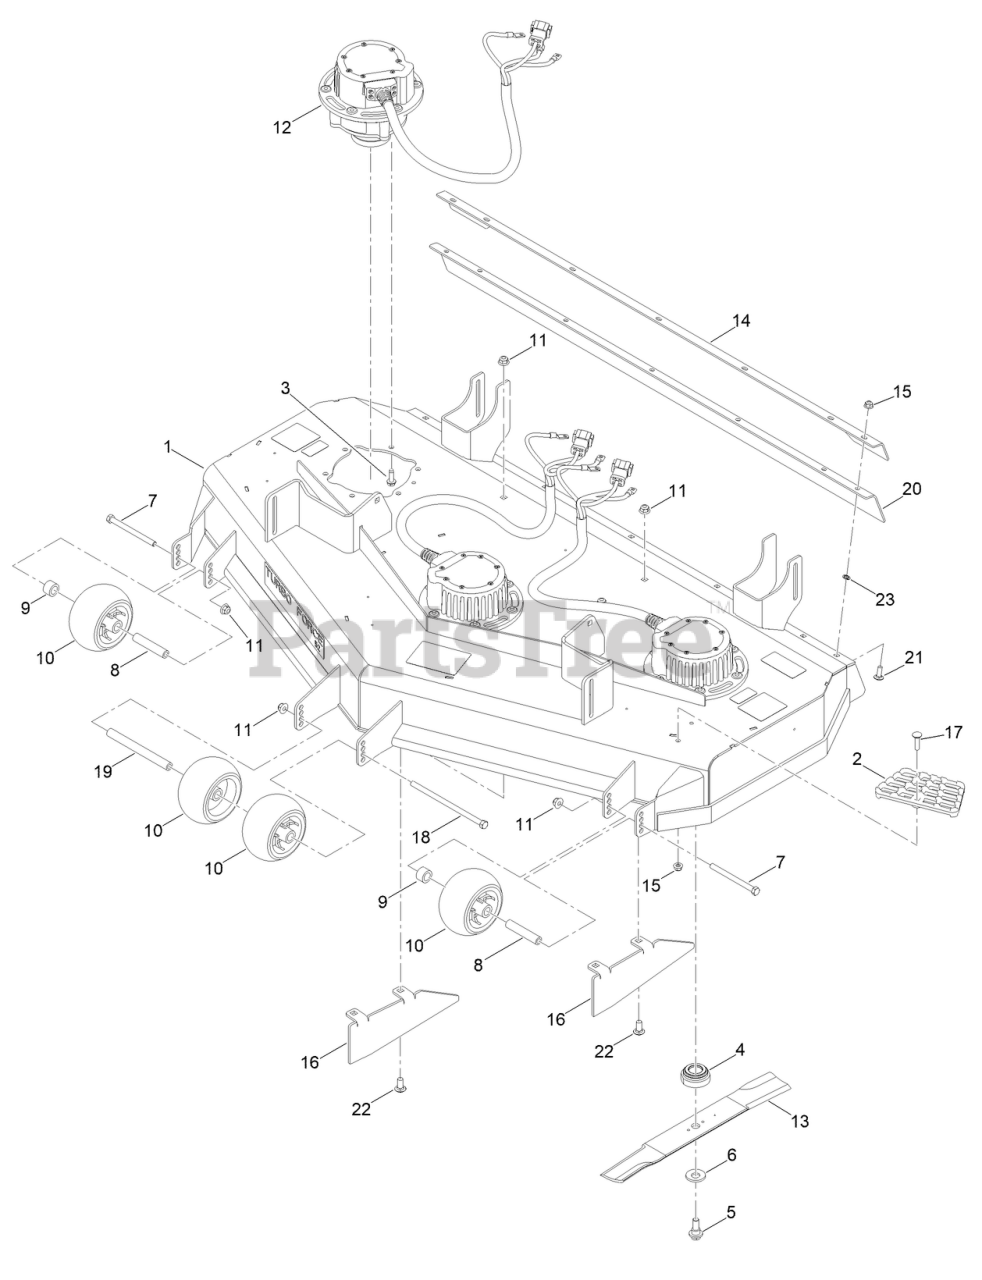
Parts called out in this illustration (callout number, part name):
1	DECK ASM-52IN, RD
2	STEP-DECK
3	SCREW-THD ROLL, HWH
4	RETAINER-BLADE
5	SCREW-SHOULDER,HWH
6	WASHER-BELLEVILLE
7	SCREW-HH
8	TUBE-SHAFTING
9	TUBE-SPACER
10	ROLLER-SCALP, ANTI
11	NUT-HF, NI
12	MOTOR/GEN-48V,
13	BLADE-18.0IN, MED SAIL
14	DEFLECTOR, BRACKET-52
15	NUT-HF, NI
16	BAFFLE-LONG
17	SCREW-CARR
18	SCREW-HH
19	SPACER-WHEEL
20	GUARD-RUBBER CTR
21	BOLT-CARR
22	SCREW-CARR
23	NUT-PUSH
